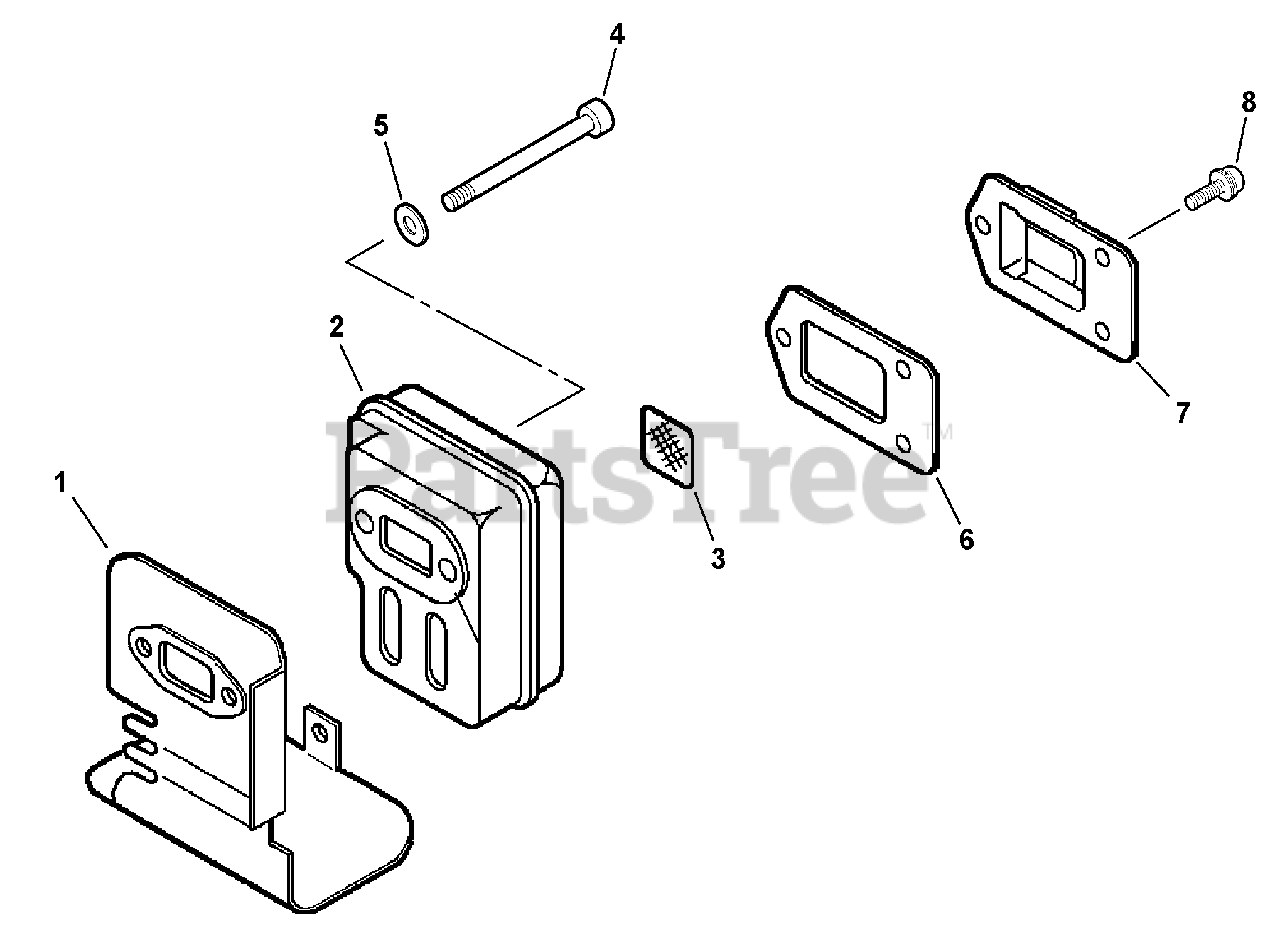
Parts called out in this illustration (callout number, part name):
1	Shield, Exhaust
3	Screen, Muffler
4	Screw 5x55
6	Gasket, Exhaust
7	Guide, Exhaust
8	Screw 4x10
